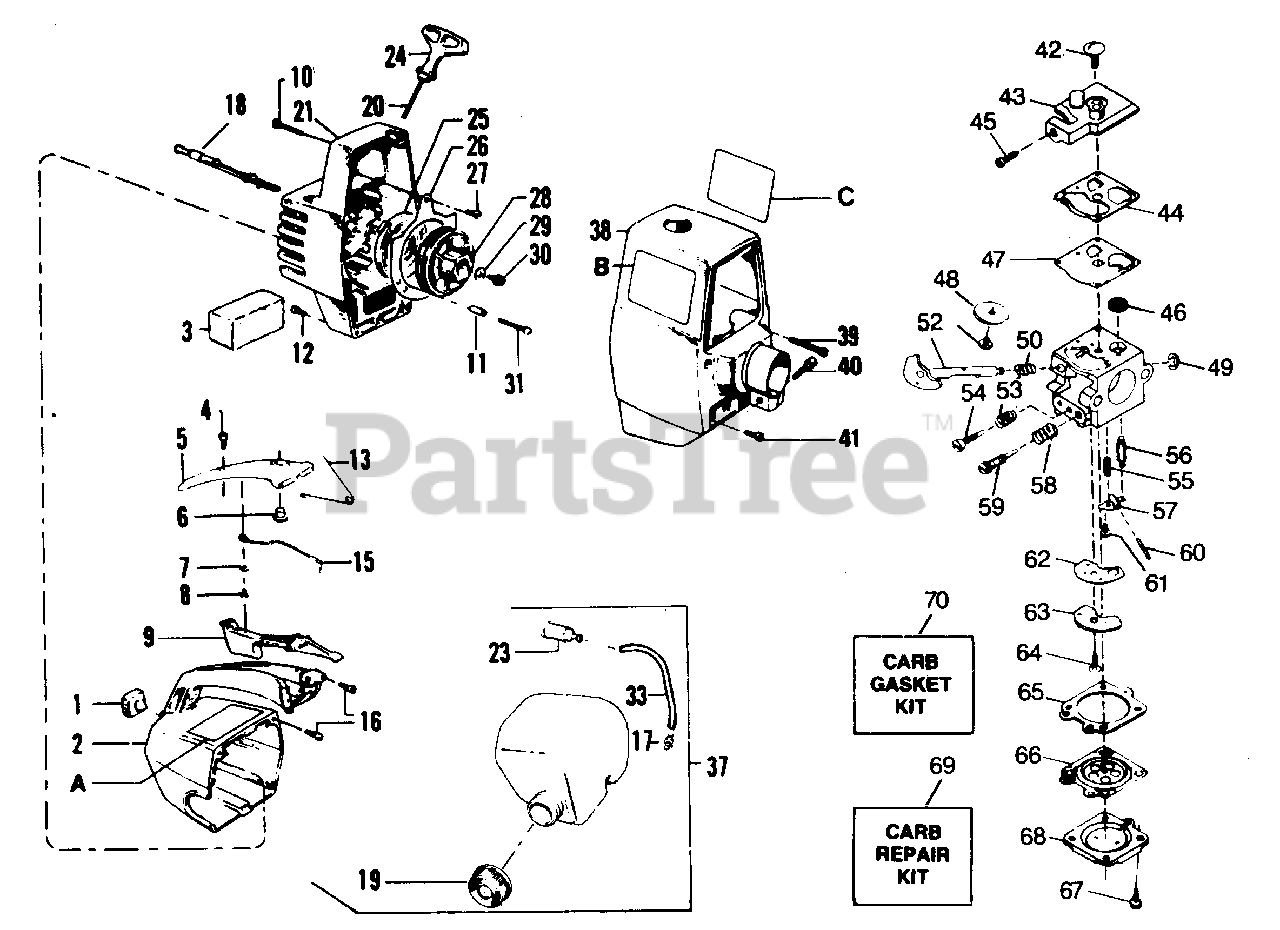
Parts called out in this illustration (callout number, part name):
1	Bumper-Fuel Tank Housing
2	Handle & Fuel Tank Housing
3	Air Filter
4	Screw-#8-16x3/4"-Pan Hd. Handle Cover
5	Handle Cover
6	Kill Switch
9	Throttle Trigger
10	Screw-#10-24 x 1-1/2"-Sems-Fan Housing-Top
11	Air Baffle Spacer
12	Screw-#10-24x5/8"-Sems-Fan Housing-Bottom
13	Spring-Trigger
15	Kill Switch Spring
16	Screw-#10-14x3/4"-Pan Head-Fan Hsg. to Handle & Fuel Tank
17	Fuel Line Fitting
18	Choke Knob
19	Fuel Cap Assembly
20	Rope Kit
21	Fan Housing Kit
23	Fuel Pick-up Assembly
24	Starter Handle
25	Starter Recoil Spring
26	Air Baffle
27	Screw-#10-14x3/8"-Pan Hd.-Air Baffle
28	Starter Pulley
29	Washer-Starter Pulley
30	Screw-#10x3/4" Hex Washer Hd.-Starter Pulley
31	Screw-#10-14x1-3/16" Air Baffle/Pump
31	, Mounting
33	Line Kit
37	Fuel Tank Assembly
39	Screw-#10-24x1-1/3"-Fil Hd.-Shroud (Top)
40	Pinch Clamp Bolt
41	Screw-#10-24x5/8"-Fil Hd.-Shroud (Bottom)
42	Screw-Pump Cover
43	Pump Cover Ass'y.
44	Gasket-Pump
45	Screw-Idle Adjustment
46	Screen Inlet
47	Diaphragm-Pump
48	Valve-Throttle
49	Clip-Throttle Shaft
50	Spring-Throttle Return
51	Screw-Throttle Valve
52	Shaft-Assembly Throttle
53	Spring-Idle Needle
54	Needle-Idle
55	Spring-Metering Lever
56	Valve-Inlet Needle
57	Lever-Metering
58	Spring-Hi Speed Needle
59	Needle-High Speed
60	Pin-Metering Lever
61	Screw-Metering Lever Pin
62	Gasket-Circuit Plate
63	Plate-Circuit
64	Screw-Circuit Plate
65	Gasket-Metering Diaphragm
66	Diaphragm Assembly-Metering
67	Screw Assembly-Metering Cover & Throttle Shaft Clip
68	Cover-Metering Diaphragm
69	Kit-Carb Kwik Repair
70	Kit-Carb Gasket/Diaphragm
A	Decal-Starting Instructions (Not a serviceable part)
B	Decal-Shroud (Right)
C	Decal-Shroud (Left)
